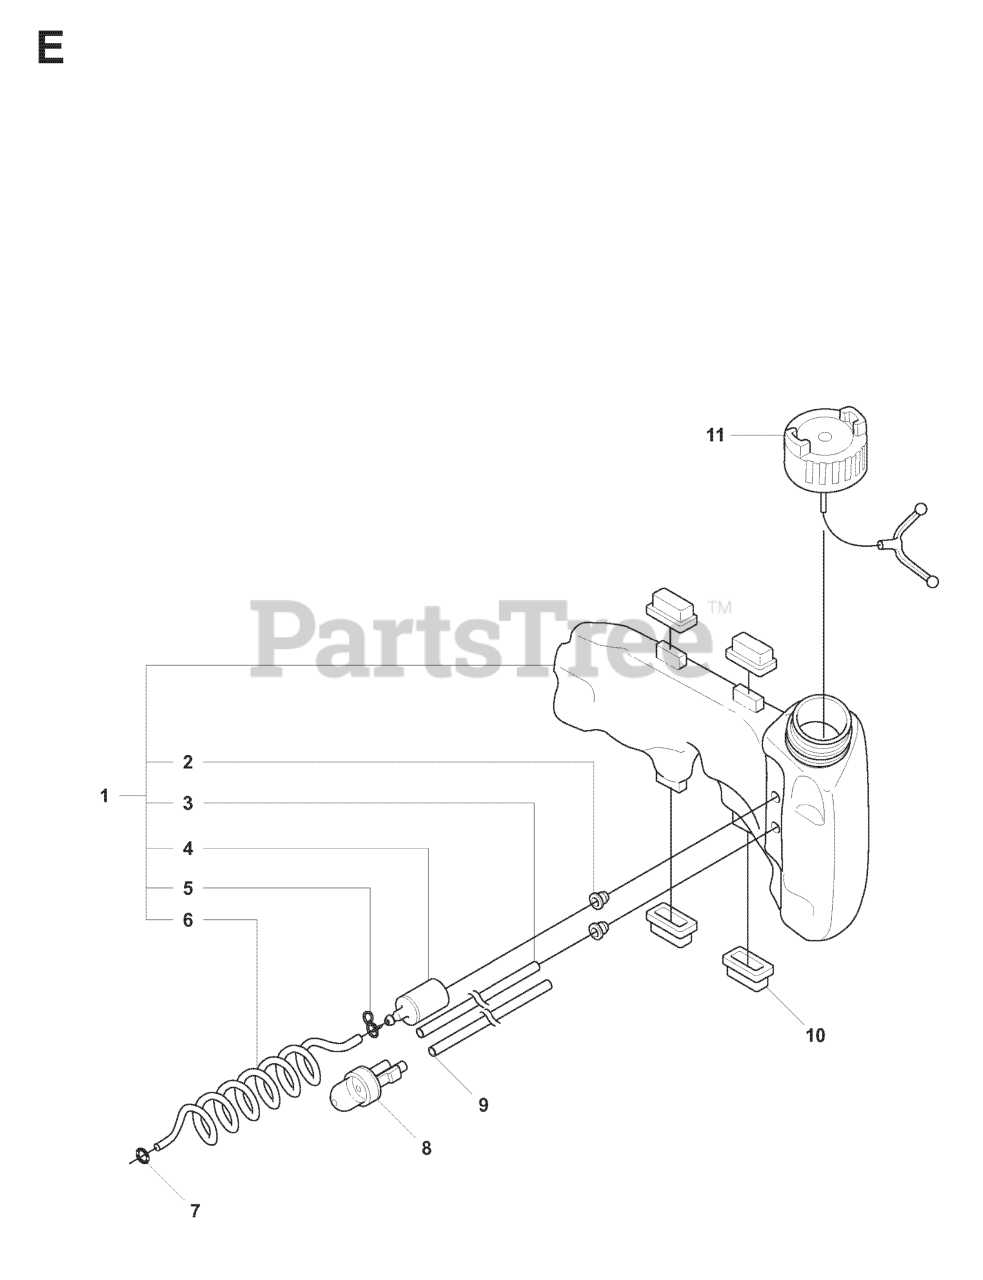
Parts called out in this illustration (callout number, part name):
2	FUEL TANK BUSHING
3	HOSE.FUEL L=102
4	RP FUEL FILTER
5	HOSE CLAMP
6	FUEL HOSE
8	AIR PURGE BUBBLE
9	HOSE.FUEL L=102
11	%FUEL CAP
